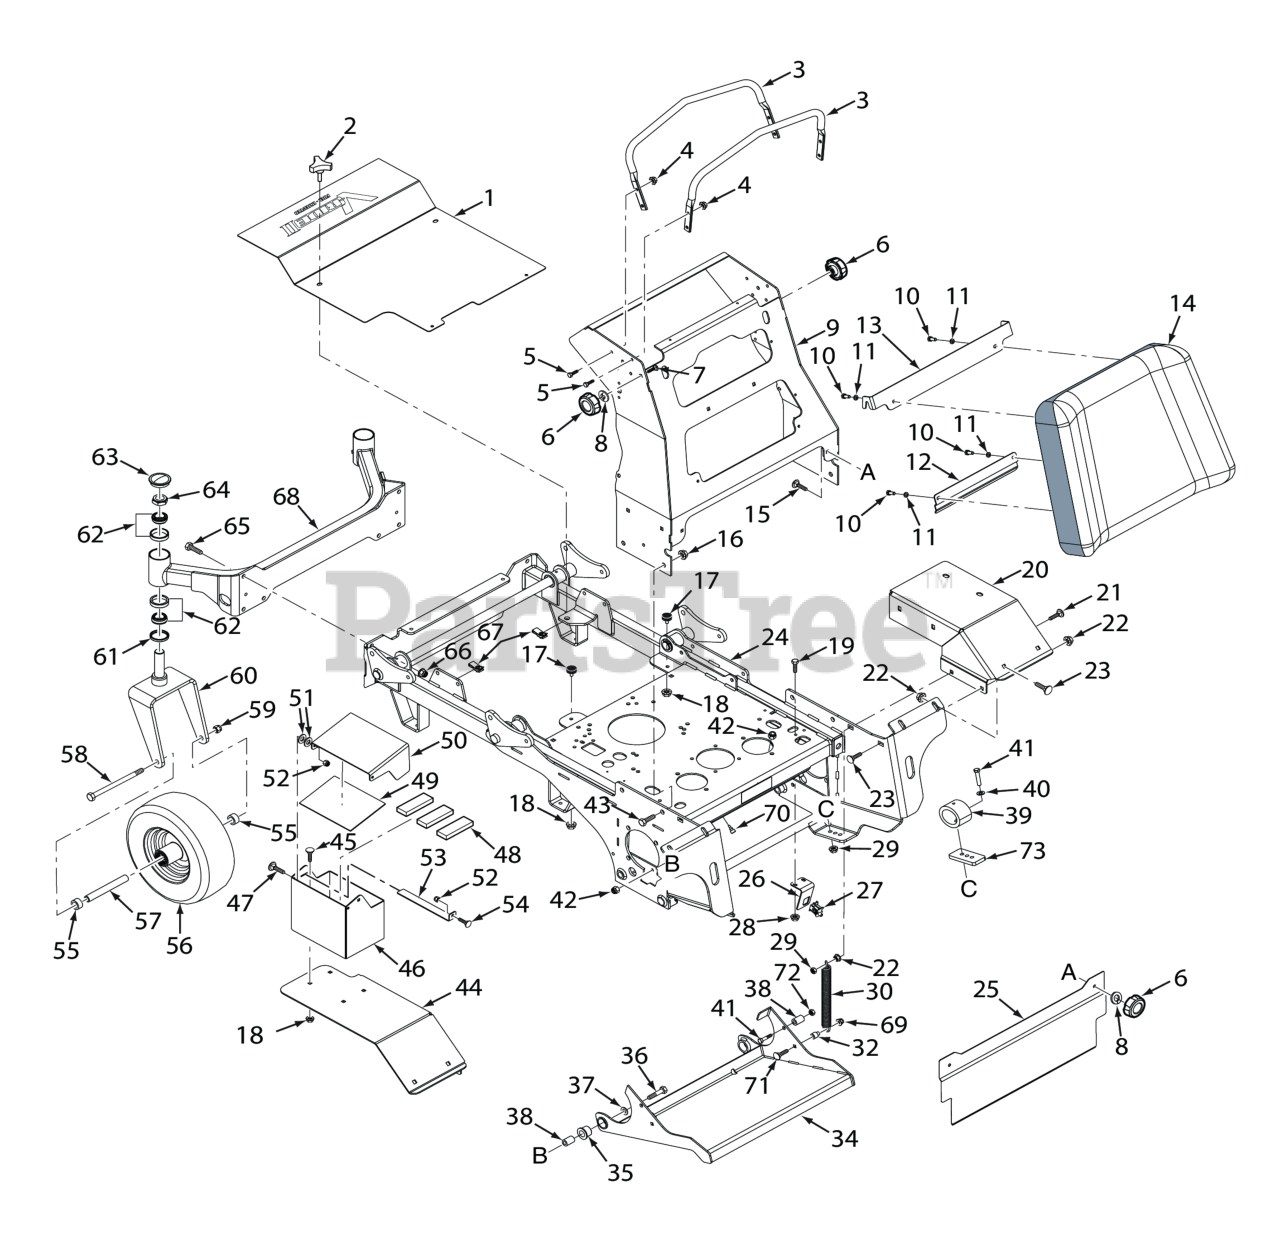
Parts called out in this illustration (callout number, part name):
1	Belt Cover w/Decals
2	Knob, w/stud 3/8-16 x 1-1/4"
3	Reference Bar
4	Nut, Serrated Flange 5/16-18 (Right Front Engine Mounting, Briggs and Kohler Only)
5	BOLT, SERRATED FLANGE HEX HEAD 5/16-18 X 3/4"
6	Knob, 5/16-18
7	Bolt, Carriage 5/16-18x1" (large frame units only)
8	Nut, Push-On 5/16-18
9	Handlebar Weldment, SVRII
10	BOLT, SERRATED FLANGE HEX HEAD 5/16-18 X 3/4"
11	Lockwasher, 5/16 (.317 x .586 x .078) Helical Spring
12	Bracket, Knee Pad - Lower
13	Bracket, Knee Pad - Upper
14	Operator Pad Assy, SVRII (INCL. 10,11,12,13)
15	Bolt, 5/16-18 x .75 RHSN Carriage
16	Locknut, 1/2-13 Spiral Lock
17	Bumper, Rubber 5/16-18 x 5/8"
18	Nut, Serrated Flange 5/16-18 (Right Front Engine Mounting, Briggs and Kohler Only)
19	BOLT, HEX HEAD, 1/4-20 X 3/4 GR.5
20	Fender, RH
21	Bolt, RDHD Carr. 3/8-16 x 1-1/2 (52" & 61")
22	NUT, 3/8-16 SERRATED FLANGE HEX HEAD
23	Bolt, Carriage 3/8-16 x 3/4"
24	Mainframe Assy. - SVRII
25	Guard, Foot -SVRII
26	Switch Bracket, Operator Presence
27	SWITCH, NEUTRAL INTERLOCK
28	NUT, 1/4-20 SERRATED FLANGE HEX HEAD
29	Nut, Flange Elastic Stop Nut, 3/8-16
30	Spring,Counter Balance
31	Bolt, Hex Head 5/16-18 x 1-1/2" (Right Front Engine Mounting, Briggs and Kohler Only)
32	Spacer, Pump Dampener
33	HEX NUT, ELASTIC STOP LOCK, 5/16-18
34	Footplate Assy, SVRII (Incl. #35)
35	Bearing, .750 I.D. Plastic
36	Capscrew, Hex Head 3/8-16 x 2.0"
37	Flatwasher, 3/8" Special (.391 x .938 x .105)
38	Yoke, Front Caster Wheel
39	Isolator, Footplate
40	Flatwasher, 3/8 (.406 x .812 x .065)
41	Bolt, Hex Head 3/8-16 x 1-3/4" (Kohler EFI)
42	HEX NUT, ELASTIC STOP LOCK, 3/8-16
43	Capscrew, 1/2-13 x 1" Serrated Flange Hex Head
44	Fender, LH
45	Bolt, 5/16-18 x .75 RHSN Carriage
46	Battery Box, Lower
47	BOLT, HEX HEAD, 1/4-20 X 3/4 GR.5
48	PAD, BATTERY SUPPORT
49	Insulation, Battery Cover (Gas Only)
50	Battery Box, Upper
51	Flatwasher, 1/4" (.312 x .750 x .065")
52	HEX, NUT, ELASTIC STOP LOCK, 1/4-20
53	Battery Box Latch
54	Serr. Fl. Hex Head CPSCR, 1/4-20 x 3/4"
55	Spacer, Caster Wheel
56	Wheel Assy, 61V, 72V (Incl. 20, 54, 55)
57	Sleeve, Caster Wheel (61V, 72A/VS)
58	Bolt, Hex Head 1/2-13 x 9-1/2" (61V & 72A/VS)
59	HEX LOCKNUT, ELASTIC STOP, 1/2-13
60	Yoke, Front Caster Wheel (61")
61	Seal, 2.00" O.D. x 1.625" Bore
62	BEARING & CUP, TAPERED SPINDLE
63	Cap, Grease
64	Nut, Hex Elastic Stop 1.0"-14
65	BOLT, HEX HEAD, 7/16-14 X 1-1/4
66	Nut, 7/16-14 Flange Elastic Stop
67	U-Nut, 3/8-16
68	Caster Support Weldment (61)
69	Nut, Flange Head Elastic Stop 5/16-18
70	BUMPER, PLUG
71	Bolt, Carriage, 5/16-18 x 1½"
72	Bolt, Hex Head 3/8-16 x 1" Ser. Flg.
73	Riser
